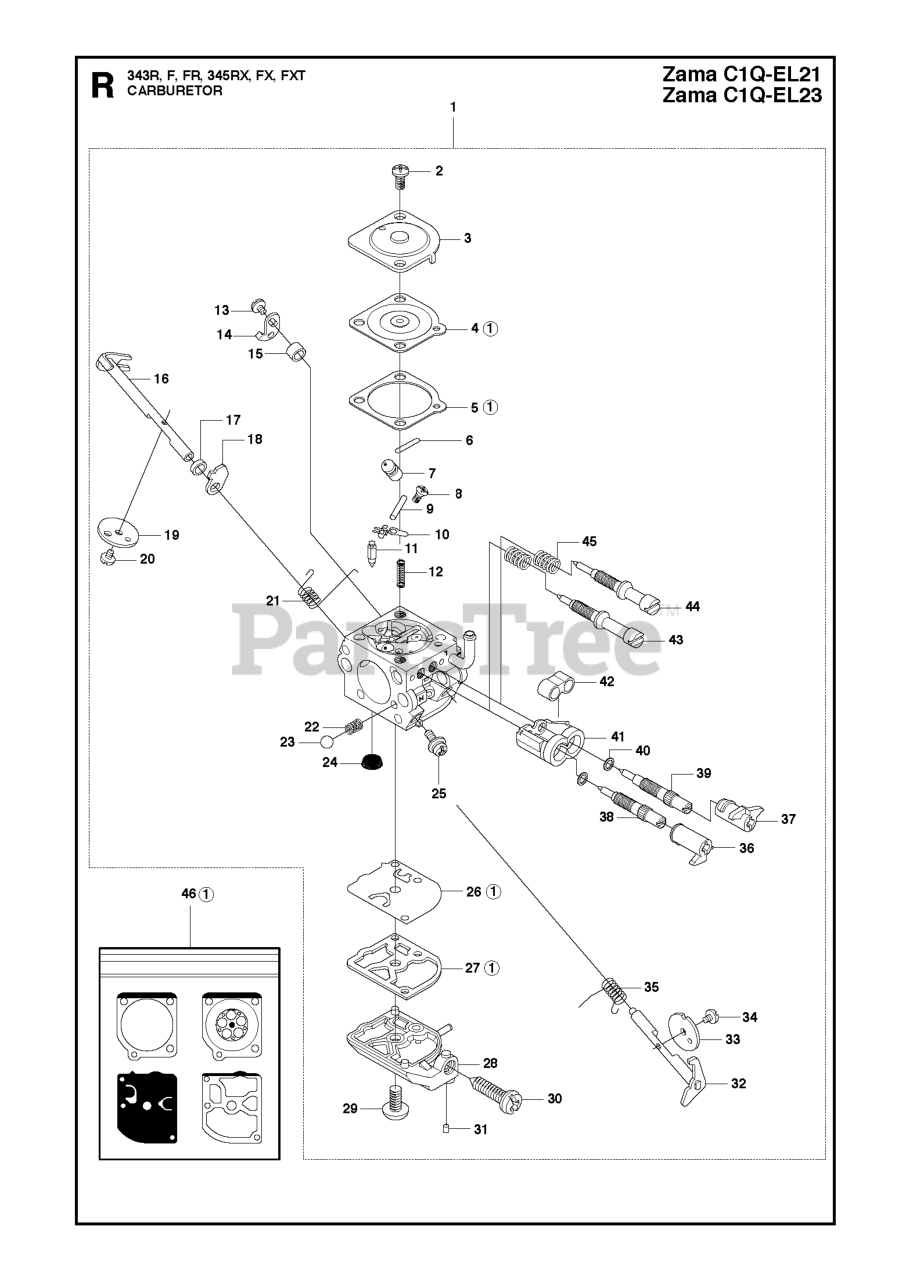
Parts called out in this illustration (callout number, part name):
1	CARBURETOR
4	METERING DIAPHRAGM
5	GASKET METERING SIDE
9	PIN RETAINING SCREW
11	INLET NEEDLE
12	SPRING
16	CHOKE SHAFT
19	DISC
26	PUMP DIAPHRAGM
27	GASKET
32	THROTTLE SHAFT
33	THROTTLE FLAP
36	LIMITER CAP
37	LIMITER CAP
38	NEEDLE HIGH SPEED
39	NEEDLE LOW SPEED
40	WASHER
41	SLEEVE
42	SLEEVE
43	SCREW
44	IDLE SCREW
45	SPRING
46	GASKET SET
